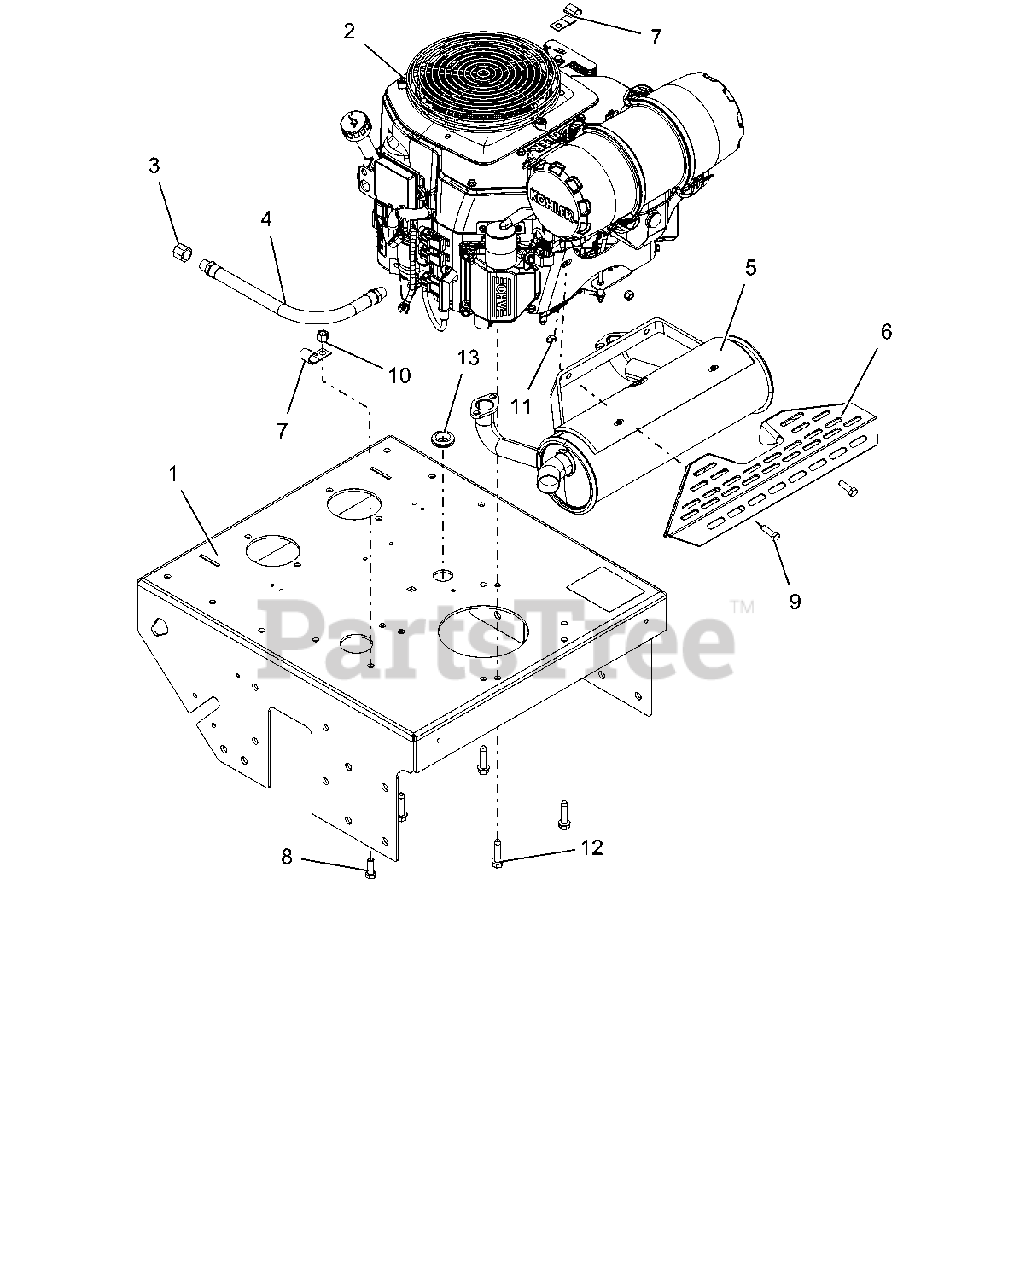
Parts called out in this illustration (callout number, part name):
1	ASSM, 48-52" FRAME W/DECALS
2	ENGINE, KOHLER PVC680 EFI LP
3	PIPE, CAP 3/8 NPT FEMALE
4	HOSE, HYD .38-11-OK M6N0-M6N0
5	MFLR, KOHLER
6	GUARD, HEAT SHIELD (BLACK)
7	P-CLIP, .500 INSULATED
8	BLT-HEX .38-16X1.00 GR5 YWZC
9	BLT-HEX .31-18X1.00 GR5 YWZC
10	NUT-LK-NYL .38-16 YWZC
11	NUT-LK-NYL .312-18 YWZC
12	SCR-TAP .38-16X1.50 HWH TR YZ
13	GROMMET:RUB:.88IDx1.38ODX.14GR
